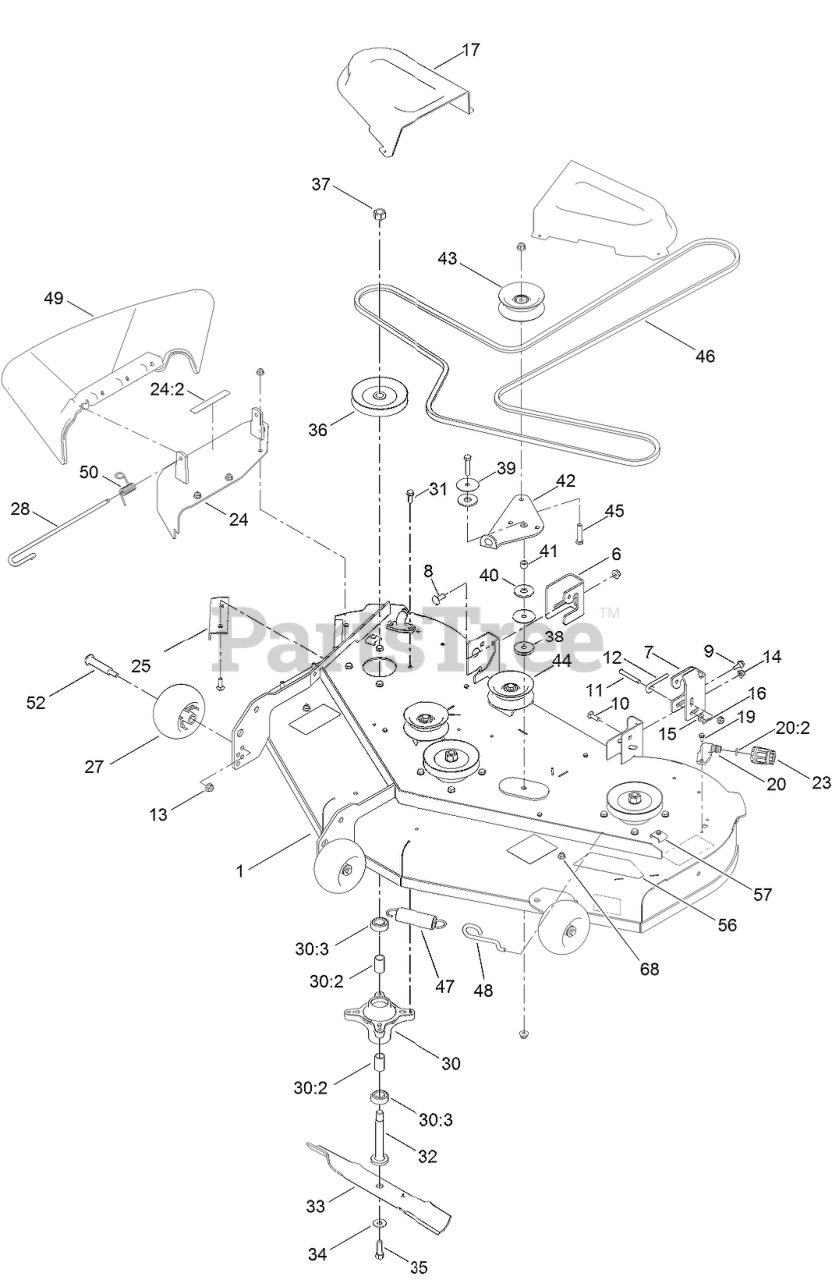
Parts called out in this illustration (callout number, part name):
1	DECK AND DECAL ASM
6	BRACKET-HANGER, RH
7	BRACKET-HANGER, LH
8	BOLT-CARR
9	SCREW-SHOULDER,HWH
10	SCREW-CARR
11	PIN-CLEVIS
12	ROD-LEVEL, DECK
13	NUT-HF, NI
14	NUT-HF, NI
15	WASHER-PLAIN
16	PIN-COTTER
17	COVER-BELT
19	SCREW-HWH
20	FITTING-WASHOUT
20:2	O-RING
23	CONNECTOR-HOSE
24	COVER ASM W/DECAL
24:2	DECAL-DANGER
25	BAFFLE-CUTOFF
27	ROLLER-SCALP, ANTI
28	PIN-CHUTE
30	SPINDLE ASM
30:2	SPACER
30:3	BEARING-BALL
31	SCREW-TAPTITE
32	SHAFT-SPINDLE
33	BLADE-HI LIFT
34	WASHER-BELLEVILLE
35	SCREW-HH
36	PULLEY
37	NUT-HEX
38	WASHER-PLAIN
39	WASHER
40	WASHER-FRICTION, COMPOSITE
41	SPACER
42	ARM-IDLER
43	PULLEY-IDLER, FLAT
44	WASHER-FLAT
45	SCREW-HH
46	V-BELT
47	SPRING-EXTENSION
48	HOOK-RETURN, SPRING
49	DEFLECTOR-DISCHARGE
50	SPRING-TORSION
52	BOLT-SHOULDER
56	DECAL-DECK
57	SCREW-TAPTITE
68	SCREW-HH
